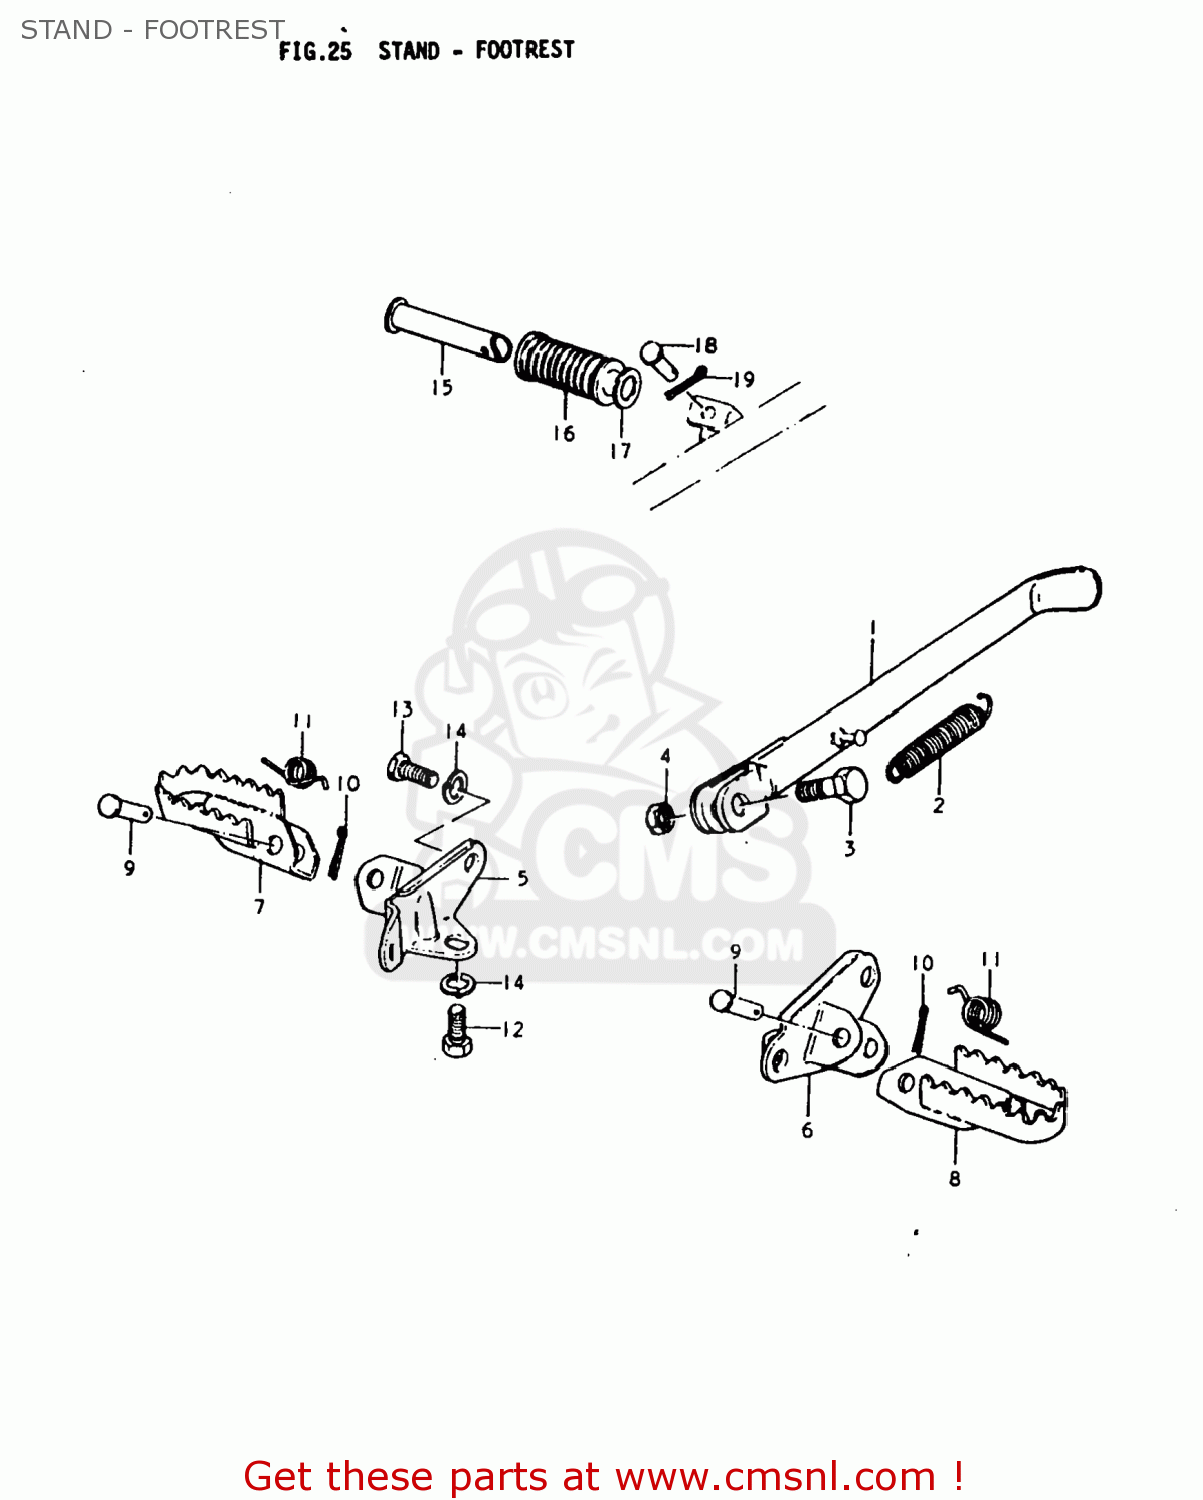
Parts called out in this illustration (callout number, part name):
1	STAND,SIDE
2	SPRING
3	BOLT(10X30)
4	NUT
5	BAR,FRONT FOOTREST
6	HOLDER,FRONT FOOTREST
7	FOOTREST,FRONT
8	FOOTREST
9	PIN
10	PIN 20X20
11	SPRING
12	BOLT
13	BOLT 8X16
14	WASHER,LOCK,8.
15	BAR,FOOTREST RUBBER
16	RUBBER,PILLION FOOTREST
17	WASHER (19.5X32X2)
18	PIN
19	PIN 20X20
